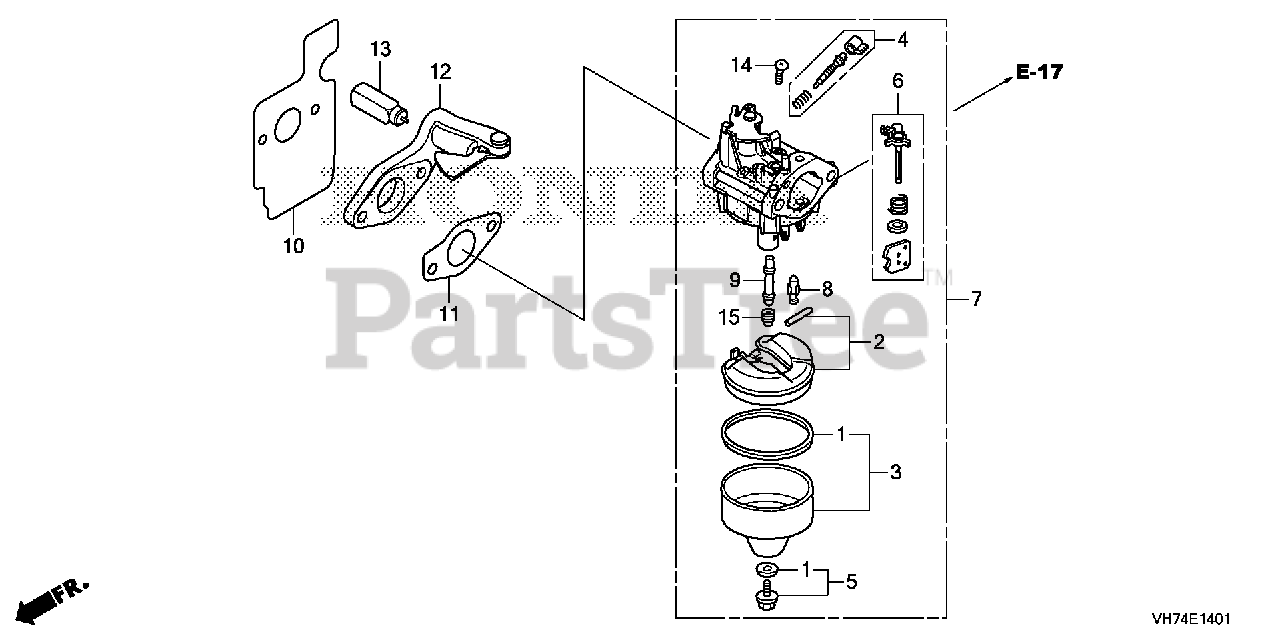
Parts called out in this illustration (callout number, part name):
1	GASKET SET
2	FLOAT SET
3	CHAMBER SET, FLOAT
5	SCREW SET
7	CARBURETOR ASSY. (BB76G A)
8	VALVE, FLOAT (Honda Code 7934714). (CARBURETOR NO.)
9	NOZZLE, MAIN
10	GASKET, INSULATOR
11	GASKET, CARBURETOR
12	CONTROL ASSY., CHOKE
13	THERMO WAX ASSY.
14	SCREW, PAN (5X6)
15	JET, MAIN (#65) Use up to Engine SN BB30A D.
15	JET, MAIN (#68) Use up to Engine SN BB30A D.
15	JET, MAIN (#70) Use up to Engine SN BB30A D.
